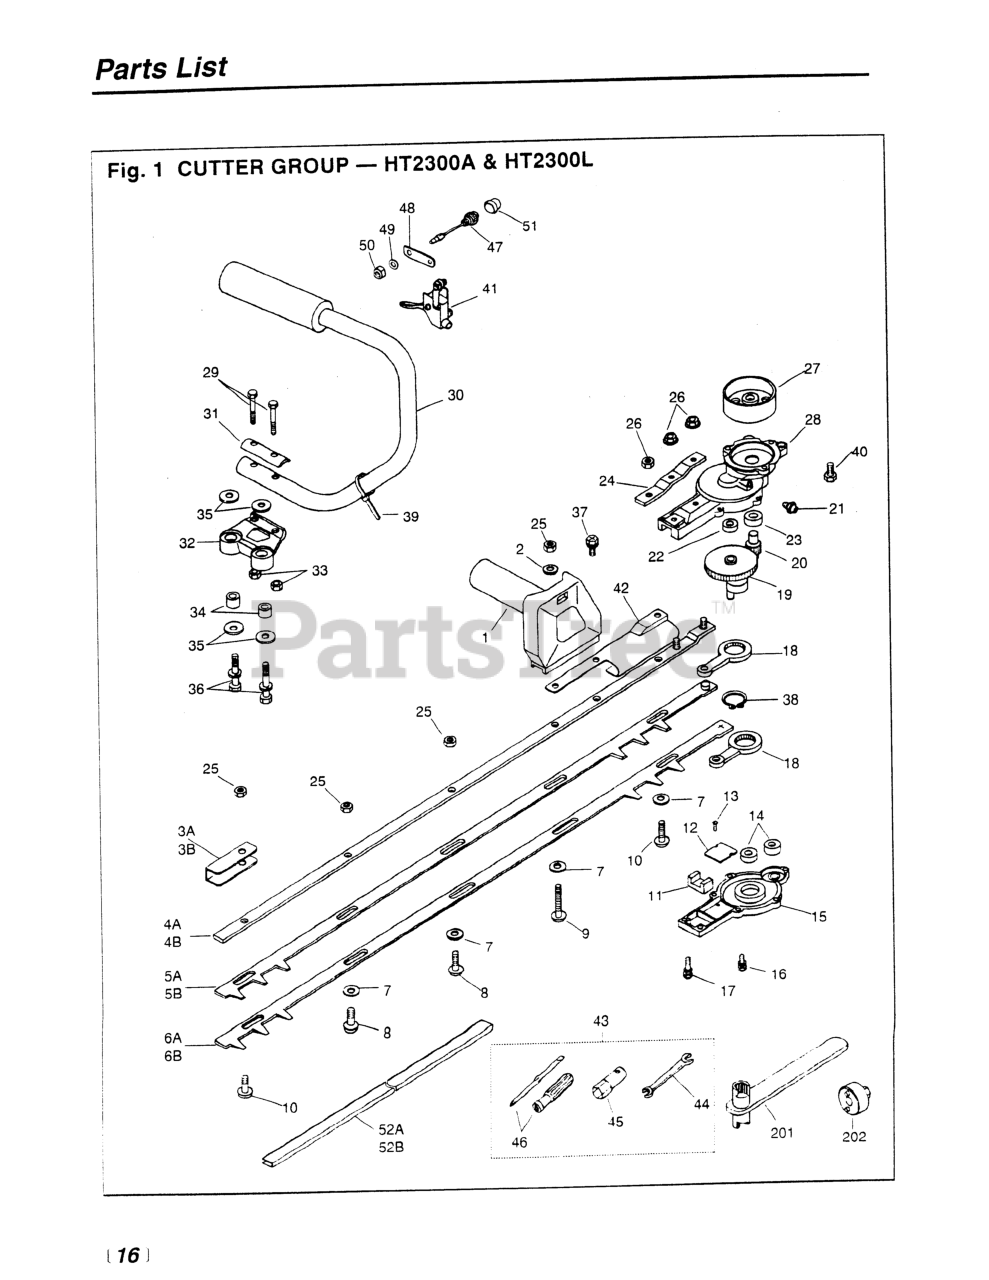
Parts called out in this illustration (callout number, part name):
1	HANDLE (RPLS -12100)
3A	REINFORCE, END
5A	BLADE, UPPER, 30
6A	BLADE, LOWER, 30
7	WASHER (RPLS 3873-11760)
11	FELT
12	PLATE
13	SCREW, M3 x 5
14	BEARING
15	CASE, LOWER
16	BOLT, M5 x 16
17	BOLT, M5 X 20
18	ROD
19	GEAR COMPLETE
20	PINION
21	FITTING, GREASE
22	BEARING
23	BEARING
24	PLATE (RPLS 3880-11130)
25	NUT, M6
26	NUT
27	DRUM, CLUTCH
28	CASE, UPPER (RPLS -11110)
29	BOLT, M5X30 (RPLS -50350)
30	HANDLE, LEFT
32	BRACKET
33	NUT (RPLS 3873-14470)
37	BOLT
38	RING, SNAP, M25 X 1.2
39	BAND, CABLE
40	BOLT, M6 X 14
41	LEVER ASSEMBLY
42	PROTECTOR
43	TOOL SET
44	SPANNER, 8 X 10 (RPLS 2540- )
45	SOCKET, HEX, 3/4
46	SCREWDRIVER
48	PLATE
49	WASHER
50	NUT
51	CAP
52A	COVER, BLADE (30
202	WRENCH (TOOL)
